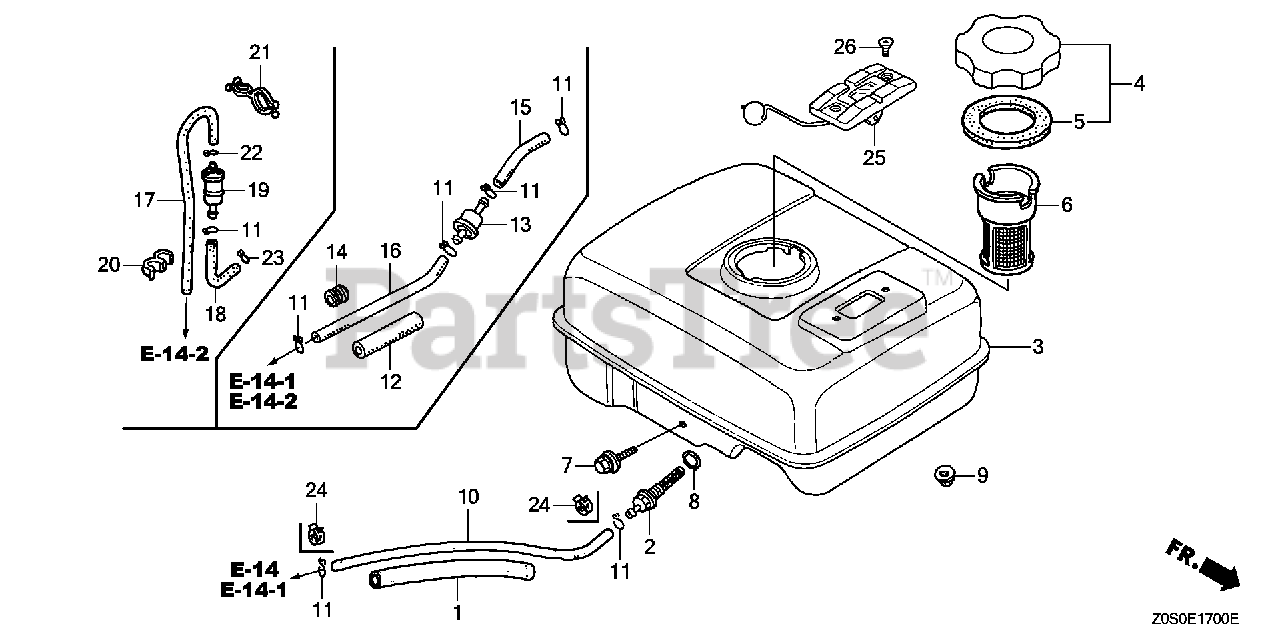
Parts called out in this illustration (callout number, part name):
1	RUBBER, SUPPORTER (107MM)
2	JOINT, FUEL TANK
3	TANK, FUEL *NH1* (BLACK)
3	TANK, FUEL *NH31* (MCKINLEY WHITE)
4	CAP, FUEL FILLER (CHROME PLATED)(RADICON)
5	GASKET, FUEL FILLER CAP (39X62X3) (RADICON)
7	BOLT, FLANGE (6X29)
8	O-RING (13.5X1.5) (ARAI)
8	O-RING (14MM) (NOK)
9	NUT, FLANGE (6MM)
10	BULK HOSE, FUEL (4.5X3000) (4.5X140)
11	CLIP, TUBE (B8)
